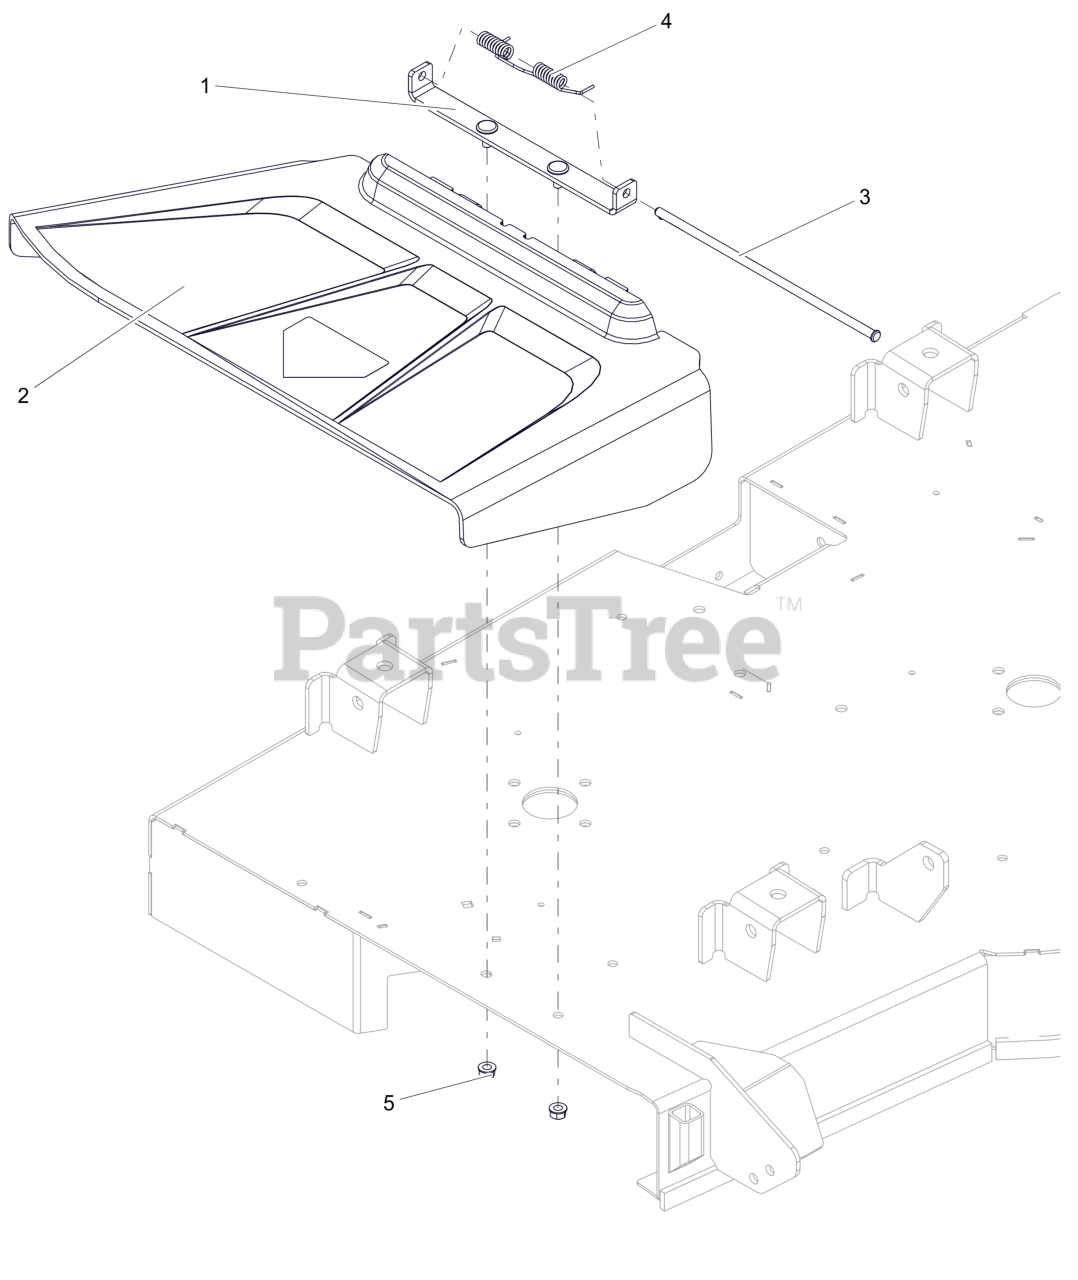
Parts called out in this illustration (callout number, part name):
2	CHUTE, SIDE DISCHARGE
3	PIN, SLIC-.312X10.45
4	SPRING-TORSION
5	NUT-LK-TOP-FLG .312-18 GF ZCC
